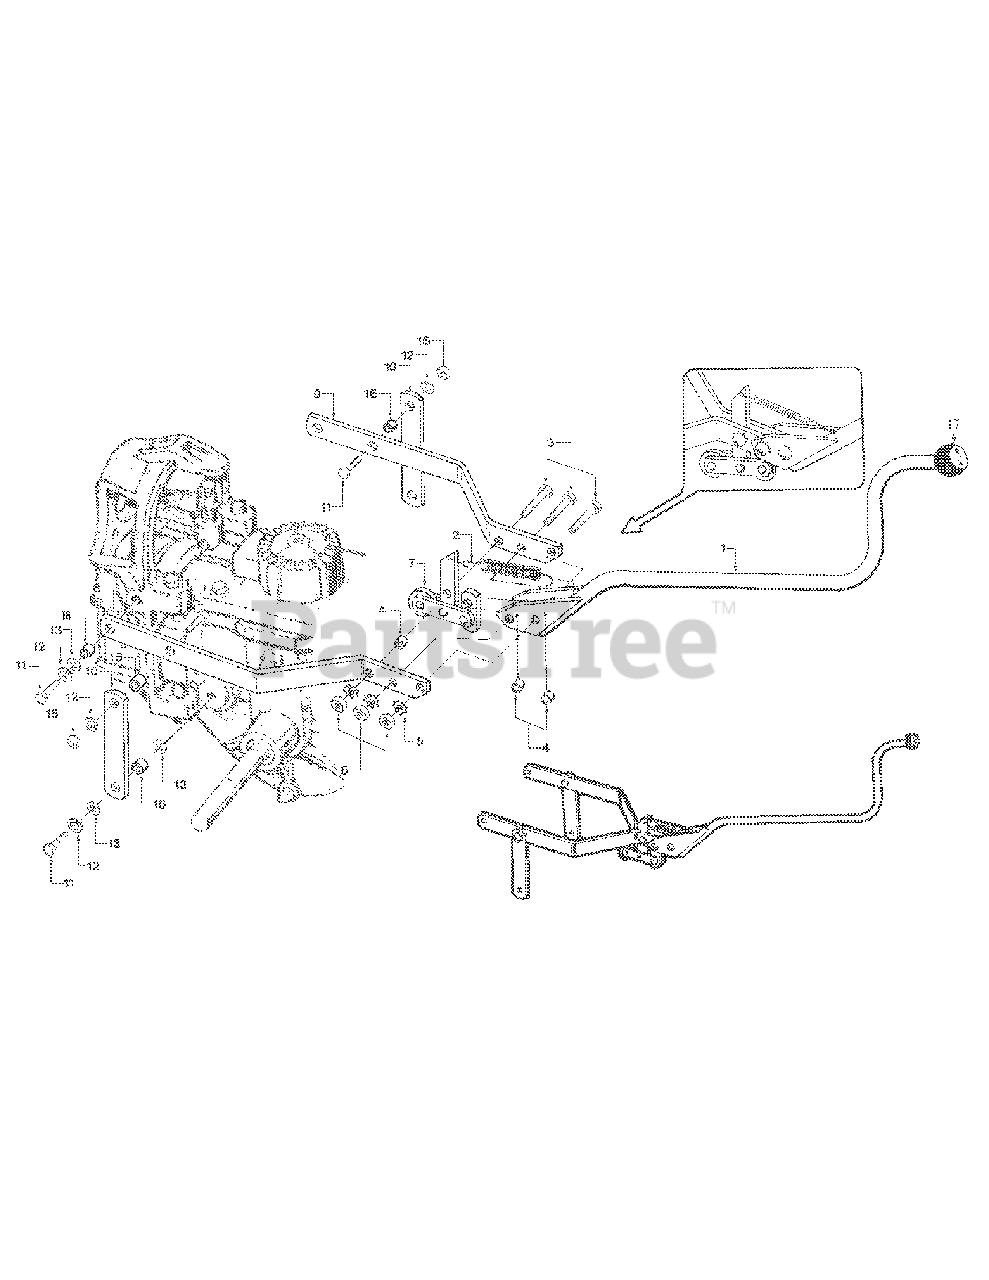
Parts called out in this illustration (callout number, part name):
1	Lever Assembly-Wheels/Tines/PTO Drive (Includes Ref 17)
2	Spring-clutch pawl
3	Bolt-hex hd., 5/16-18 x 1- 1/2"
4	Bushing-3/8"
5	Lockwasher-external tooth, 5/16"
6	Nut-hex, 5/16"-18
8	Yoke-left side
9	Yoke-right side
10	Link-yoke pivot, left & right, 6-7/8" long
11	Bolt-hex hd., 3/8-16
12	Lockwasher-spring lock 3/8"
13	Washer-flat, 3/8", S.A.E.
15	Nut-hex, 3/8"-16
16	Bushing-spacer, 19/64" (.300")
17	Knob
